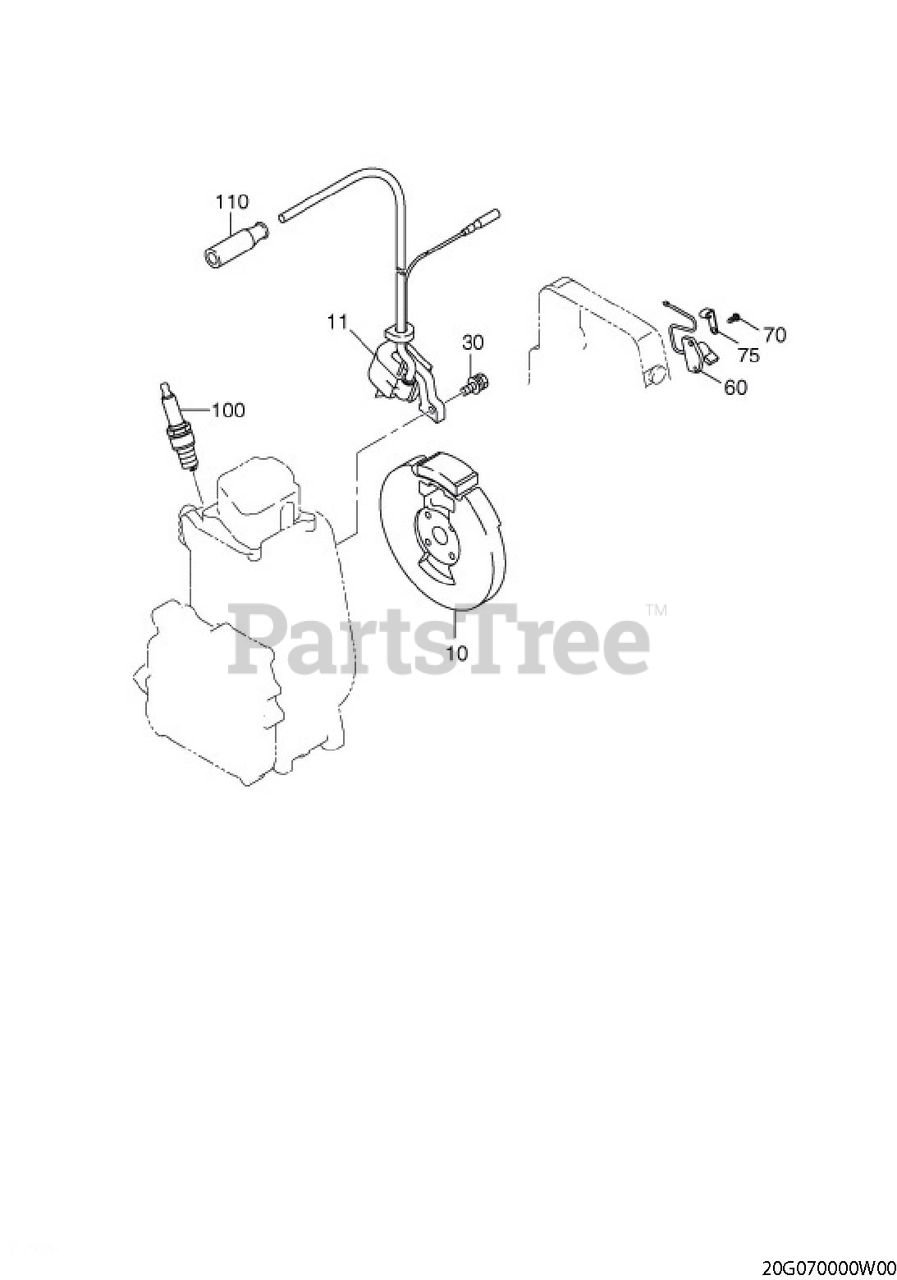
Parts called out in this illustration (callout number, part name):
11	IGNITION COIL CP
30	BOLT & WASHER AY
70	SCREW AND WASHER AY
110	SPARK PLUG CAP
